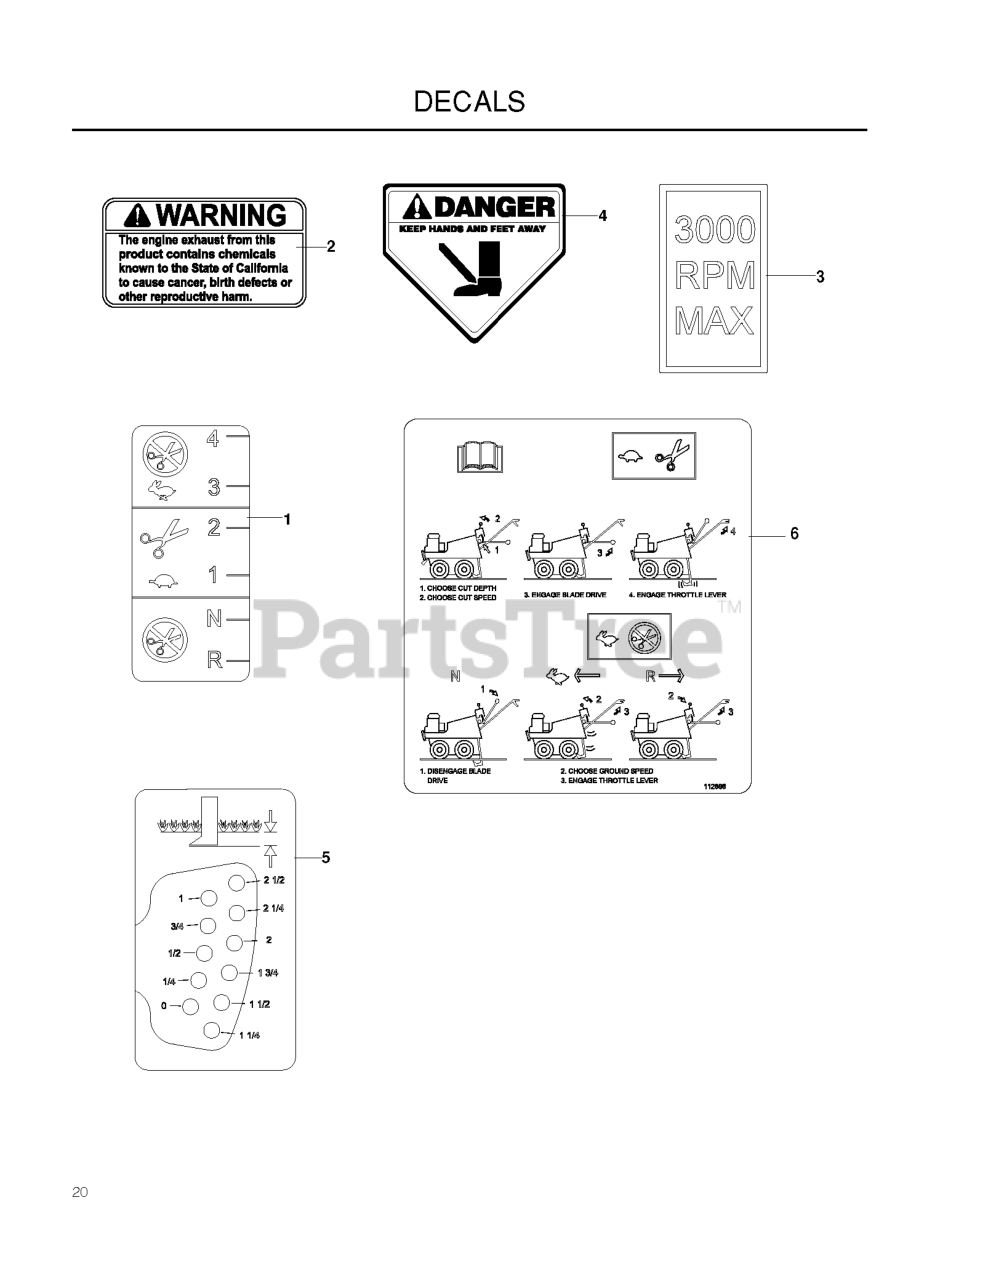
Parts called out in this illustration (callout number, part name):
1	DECAL, SHIFT
2	DECAL, PROP. 65
3	DECAL, 3000 MAX RPM, HUSQ
4	DECAL, FOOT DANGER
5	DECAL, DEPTH OF CUT
6	DECAL, OPERATION
